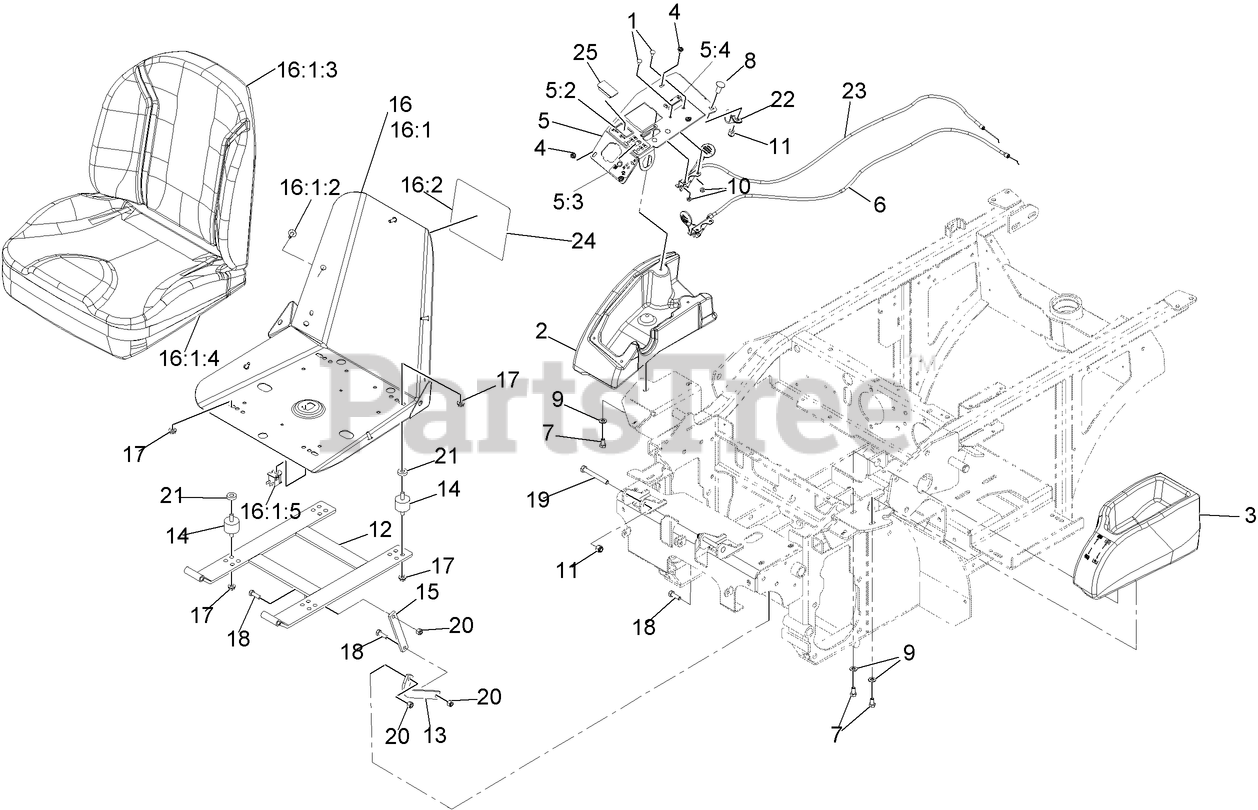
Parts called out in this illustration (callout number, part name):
1	BOLT-CARR
2	CONSOLE-RH
3	CONSOLE, LH GREY
4	SCREW-PPH
5	CONTROL PANEL ASM
5:2	Decal-Nav Console 640Kc
5:3	DECAL-SPEED CONTROL
5:4	DECAL-CHOKE
6	CABLE-THROTTLE
7	SCREW-HH
8	SCREW-CARR
9	WASHER-PLAIN
10	NUT-LOCK, NI
11	NUT-LOCK, NI
12	FRAME-SEAT
13	LINK-SEAT STOP
14	MOUNT-VIBRATION, RUBBER
15	LINK-SEAT
16	ASM-SEAT W/DECAL
16:1	ASM-Seat, Navigator
16:1:2	BOLT-SEAT
16:1:3	CUSHION-SEAT, BACK
16:1:4	COVER-SEAT BOTTOM SVC
16:1:5	SWITCH-BAIL
16:2	Decal-Service Aid
18	SCREW-HH
19	SCREW-HH
20	NUT-LOCK, NI
21	SPACER
22	CLIP-LOOM
23	CABLE-CHOKE
24	Decal-Service Aid
25	PLUG-HOLE
